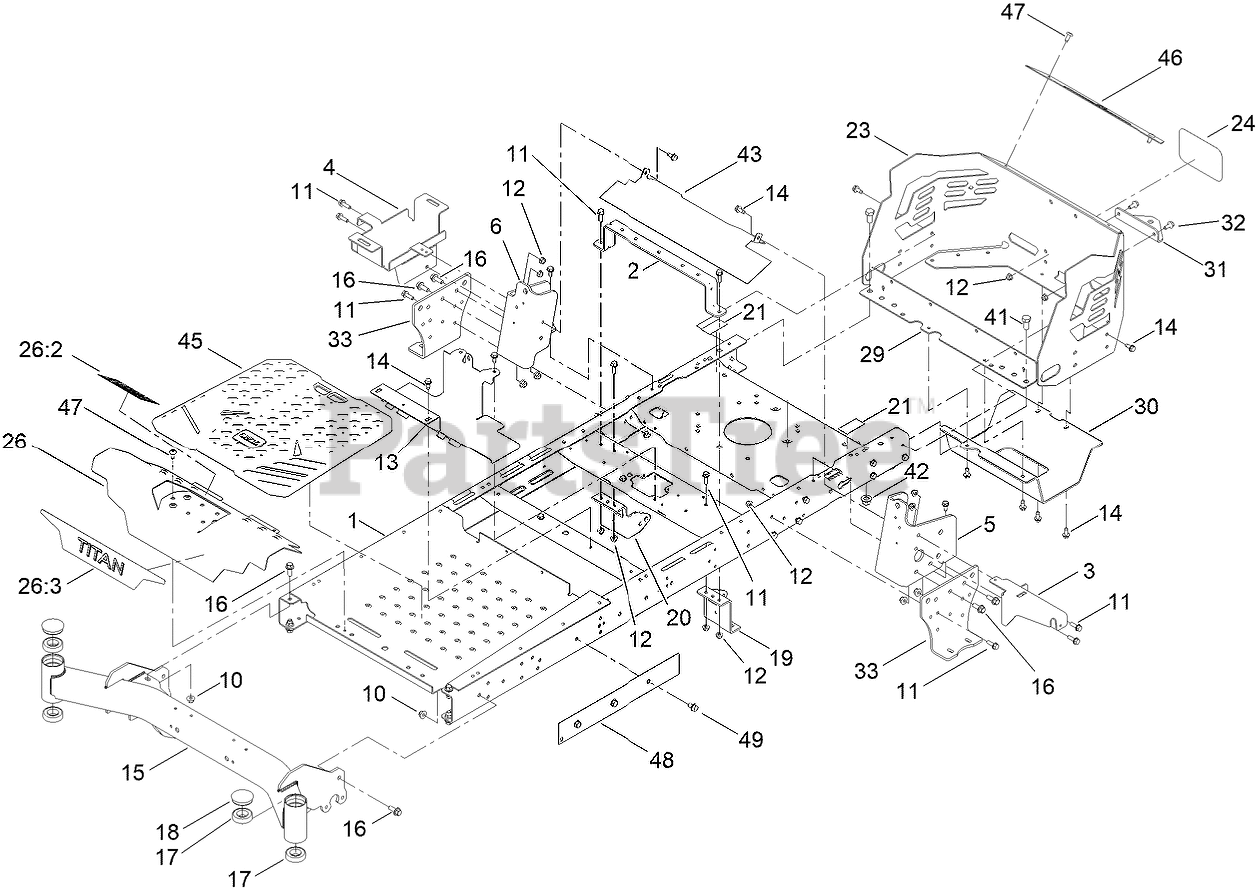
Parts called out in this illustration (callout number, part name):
1	FRAME ASM
2	BRACE-SEAT, REAR (WIDE)
3	BRACKET-SUPPORT, POD (LH)
4	TRAY-BATTERY
5	BRACKET-MOUNTING, LH
6	BRACKET-MOUNTING, RH
10	NUT-HF, NI
11	SCREW-HHF
12	NUT-HF, NI
13	BRACKET-MOUNT
14	SCREW-HWHTF
15	FRONT AXLE ASM
16	SCREW-HHF
17	BEARING-BALL
18	CAP-GREASE
19	MOUNT-HYDRO, FRONT (LEFT)
20	MOUNT-HYDRO, FRONT (RIGHT)
21	DECAL-BYPASS
23	GUARD-ENGINE
24	DECAL
26	FOOTREST-TITAN
26:2	DECAL-DANGER
26:3	DECAL-TITAN
29	CROSSMEMBER-REAR, WIDE
30	GUARD-MUFFLER
31	BRACKET-HITCH
32	SCREW-HHF
33	MOUNT-HYDRO
41	SCREW-HH
42	NUT-LOCK
45	FLOOR MAT
46	TRIM-GUARD, ENGINE
48	PLATE-FRAME
49	SCREW-HWHTF
